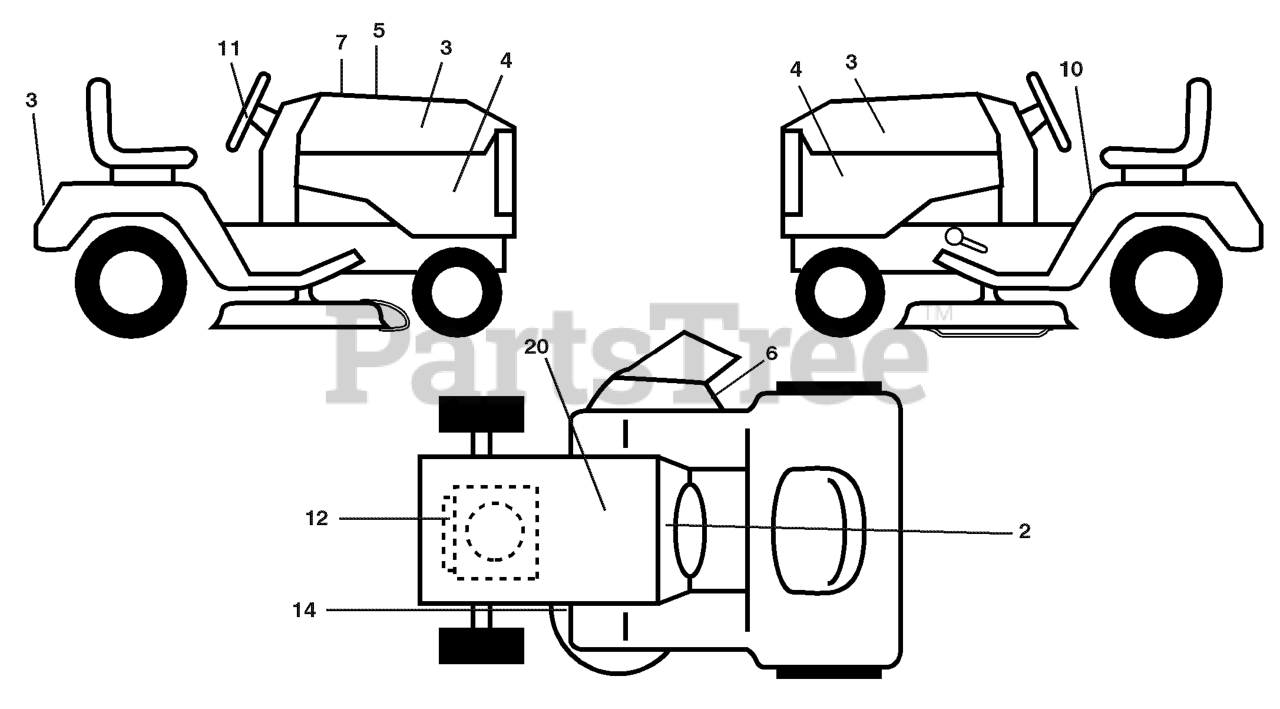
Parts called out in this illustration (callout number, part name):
3	DECAL.HOOD.NAMELOGO.HUSQ
4	DECAL.SDPNL.YTH18542.B&S.HUSQ
5	DECAL HOOD CUST. RESP.
6	DECAL.WARN.KEEP.HAND.AWAY
7	DECAL.RPL.BSM31INTK.STL42E.510
10	DECAL.FENDER.WARNING.ENG
11	DECAL.WHEEL.STRG.LGN.H
12	DECAL.ENG.BS18.5HP.INTEK.GEN
14	DECAL V BELT SCHEMATIC
20	DECAL BTRY SYMBOLS
20	DECAL.BYPASS.FENDER.CRD.LT.YT
20	DECAL HANDLE LIFT
20	PAD FOOTREST LH
20	PAD FOOTREST RH
20	Manual, Owner's
